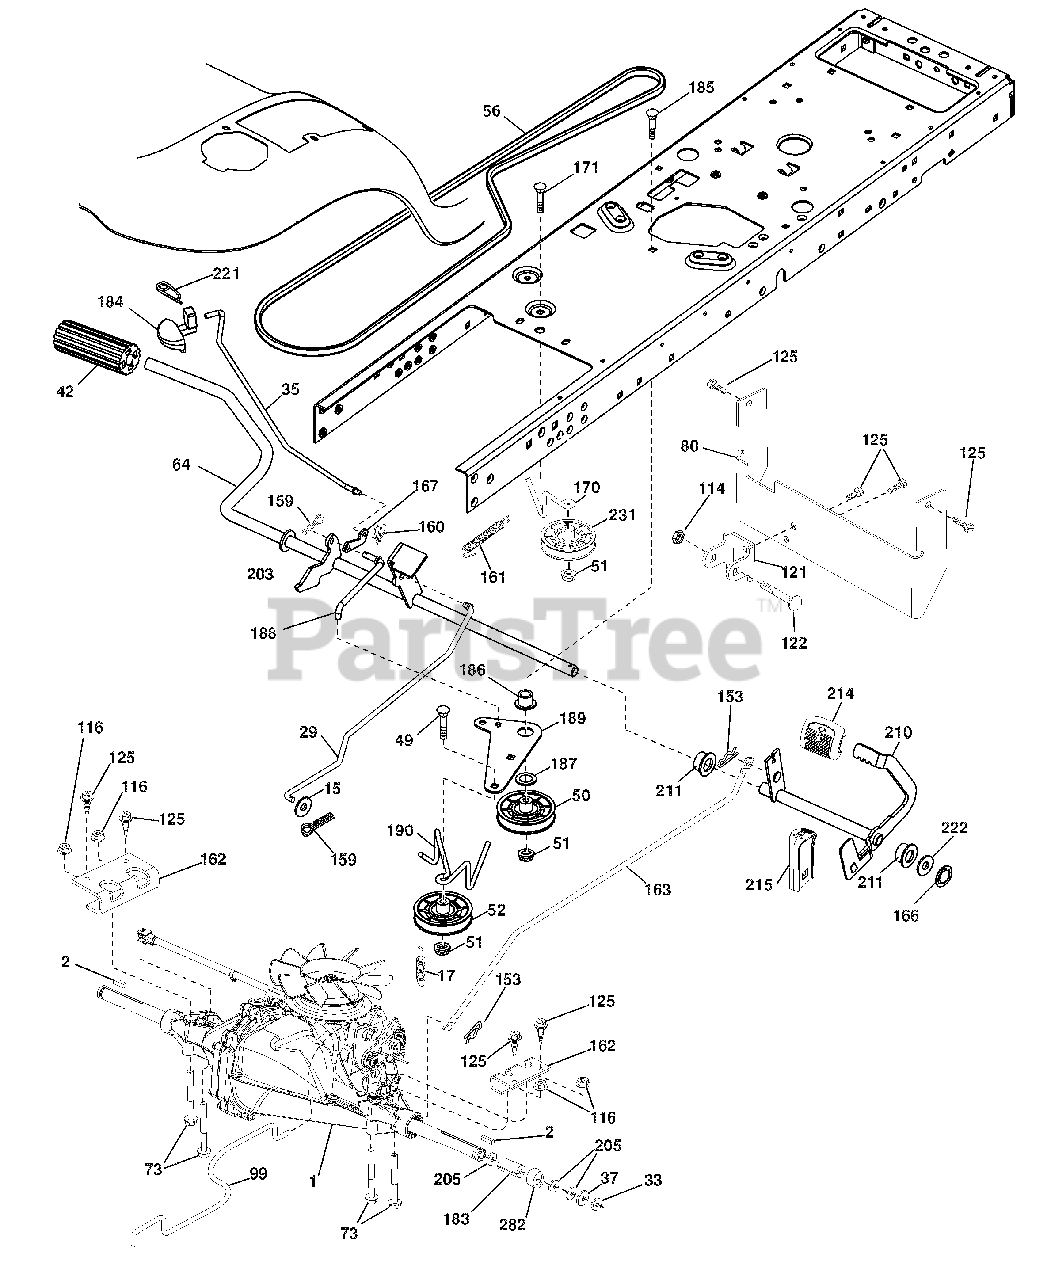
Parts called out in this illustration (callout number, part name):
2	Key Square
15	Washer 13/32 x 13/16 x 16 Ga.
17	Spring, Brake
26	Spring Return Cruise
29	Rod, Brake
35	Rod, Brake, Park
37	Washer 25/32 x 1-1/4 x 16 Ga.
42	Cover, Foot Pedal
50	Pulley Idler Flat
51	Lock Nut 3/8-16
52	Idler V-Groove 910" Offset
56	V-Belt, Drive
64	Shaft Asm. Pedal Brake Control
73	Bolt Hex 5/16-18 Gr. 5
80	Strap Torque
92	Bolt Fin Hex 5/16-18 unc x 1.25
99	Rod Spring Bypass
114	Nut Lock HX W/Ins 5/16-18
116	Nut Lock Hex Flange 5/16-18
121	Bracket Strap Torque
122	Bolt 5/16-18 x 2.50
125	Screw 5/16-18 x 3/4
143	Screw 5/16-18 x 1/2
153	Retainer Spring 1"
159	Pin Cotter 1/8 x 3/4
160	Retainer Clip
161	Spring, Return, Clutch
162	Adapter Transaxle
163	Rod Control
166	Nut Push
167	Latch Brake Parking
170	Keeper V-Idler
183	Spacer Axle
184	Handle Parking Brake
186	Spacer Retainer
187	Washer
188	Link Clutch Ground Drive
189	Bellcrank Ground Drive
190	Keeper Bellcrank Ground Drive
205	Washer 25/32 x 1-5/8 x 16 Ga.
206	Bracket Mount Latch Cruise
207	Latch Control Cruise
208	Gear Sector Control Cruise
209	Rod Control Cruise
210	Rocker Asm. Pedal Control
211	Bearing Nylon
213	Knob Control Cruise
214	Pedal Forward
215	Pedal Reverse
221	Retainer Spring Clip Handle
222	Washer 21/32 x 1-1/4 10 Ga.
231	Idler V-Groove 1.688" Offset
282	Spacer Split .800 x .350 .22" T
